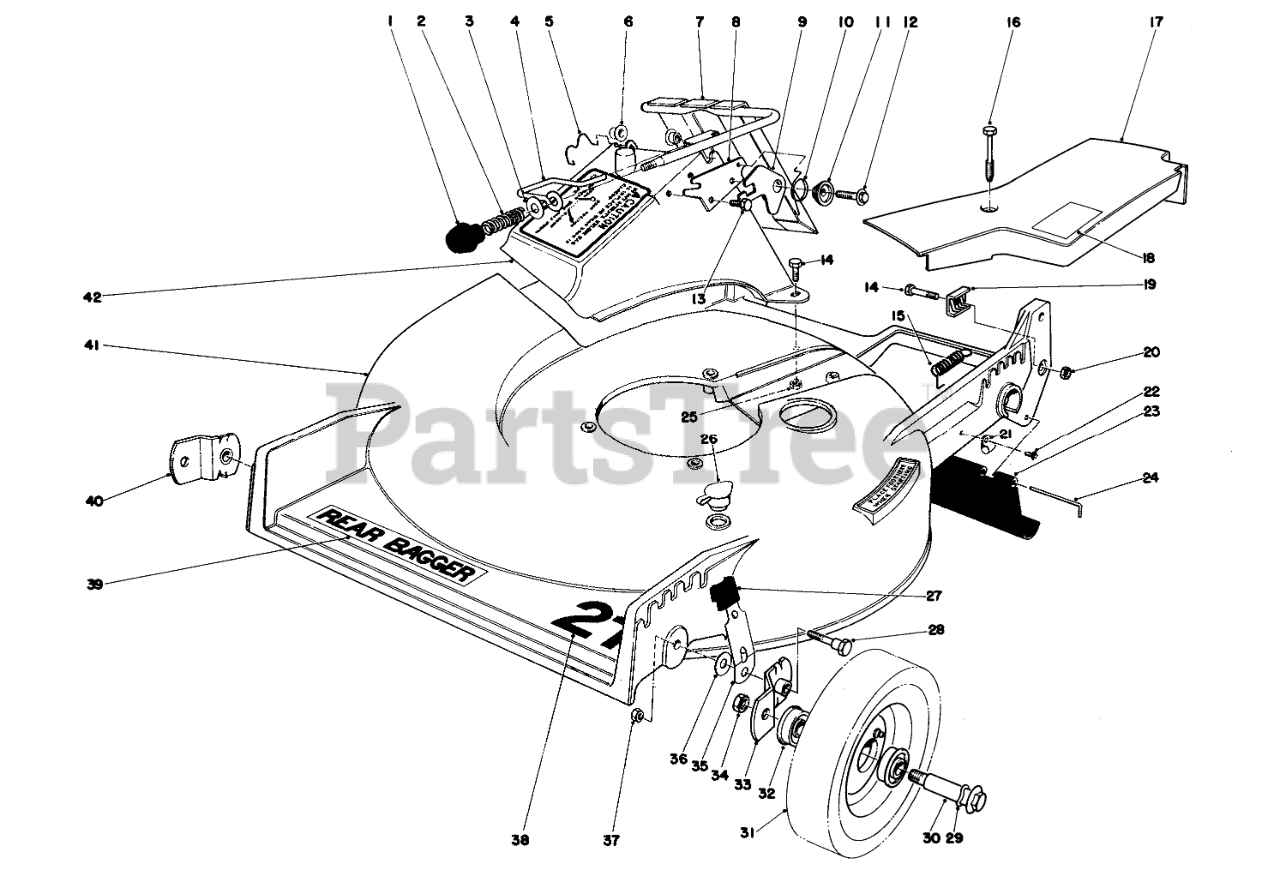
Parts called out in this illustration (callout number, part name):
2	COMPRESSION SPRING
3	WASHER
4	DOOR LATCH
5	DOOR RETAINER
6	BUSHING-NYLON
7	DOOR & HANDLE WA
8	DOOR LATCH PLATE
9	Latch Safety
10	TORSION SPRING
11	Latch Spacer
12	Screw
13	SCREW-HWH
14	SCREW-HH
15	IDLER SPRING
16	SCREW-HHFTF
17	Belt Cover
18	Sticker Grease
19	CLAMP-CABLE
20	NUT-JAM
21	CLAMP-NYLON
22	SCREW-HWH
23	SHIELD - TRAILING
24	Rod Shield
25	NUT-LOCK, NI
26	WASHOUT PLUG
27	KNOB-ARM
28	PIVOT SCREW
29	SPRING WASHER
31	Wheel & Tire Assembly (Incl. Ref. #32)
32	BEARING-BALL
33	Pivot Arm "A"
34	Nut
35	SPRING ARM ASM (R&S)
36	WASHER-PIVOT
37	Nut
38	Decal 21"
39	DECK DECAL
40	PIVOT ARM ASM B
41	Housing
42	DISCHARGE CHUTE B
